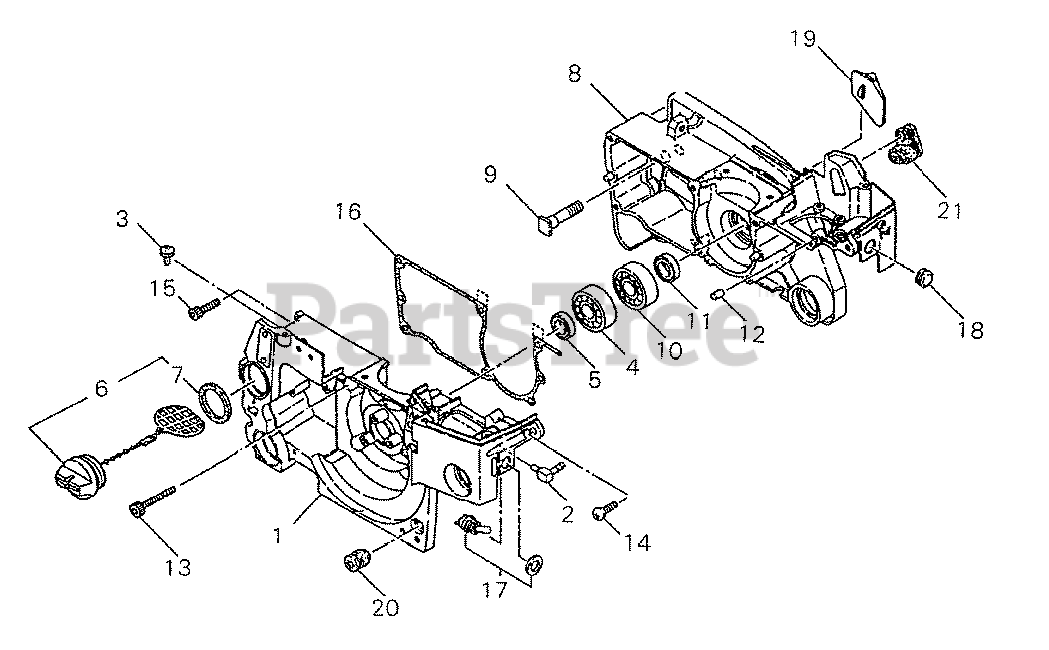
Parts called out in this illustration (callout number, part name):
1	CRANKCASE - LEFT
2	CONNECTOR, PIPE
3	VENT ASSY
4	BEARING, BALL 6201 C3
5	SEAL, OIL 12
6	CAP ASSY, OIL
7	GASKET, CAP
8	CRANKCASE - RIGHT
9	BOLT, STUD 8
10	BEARING, BALL 6201 C3
11	SEAL, OIL 12
12	PIN, LOCATING 5×10
13	BOLT 5×30
14	SCREW M5×12
15	BOLT M5×18
16	GASKET
17	SWITCH ASSY
18	PLUG
19	STOPPER
20	SUPPORT
21	GROMMET
